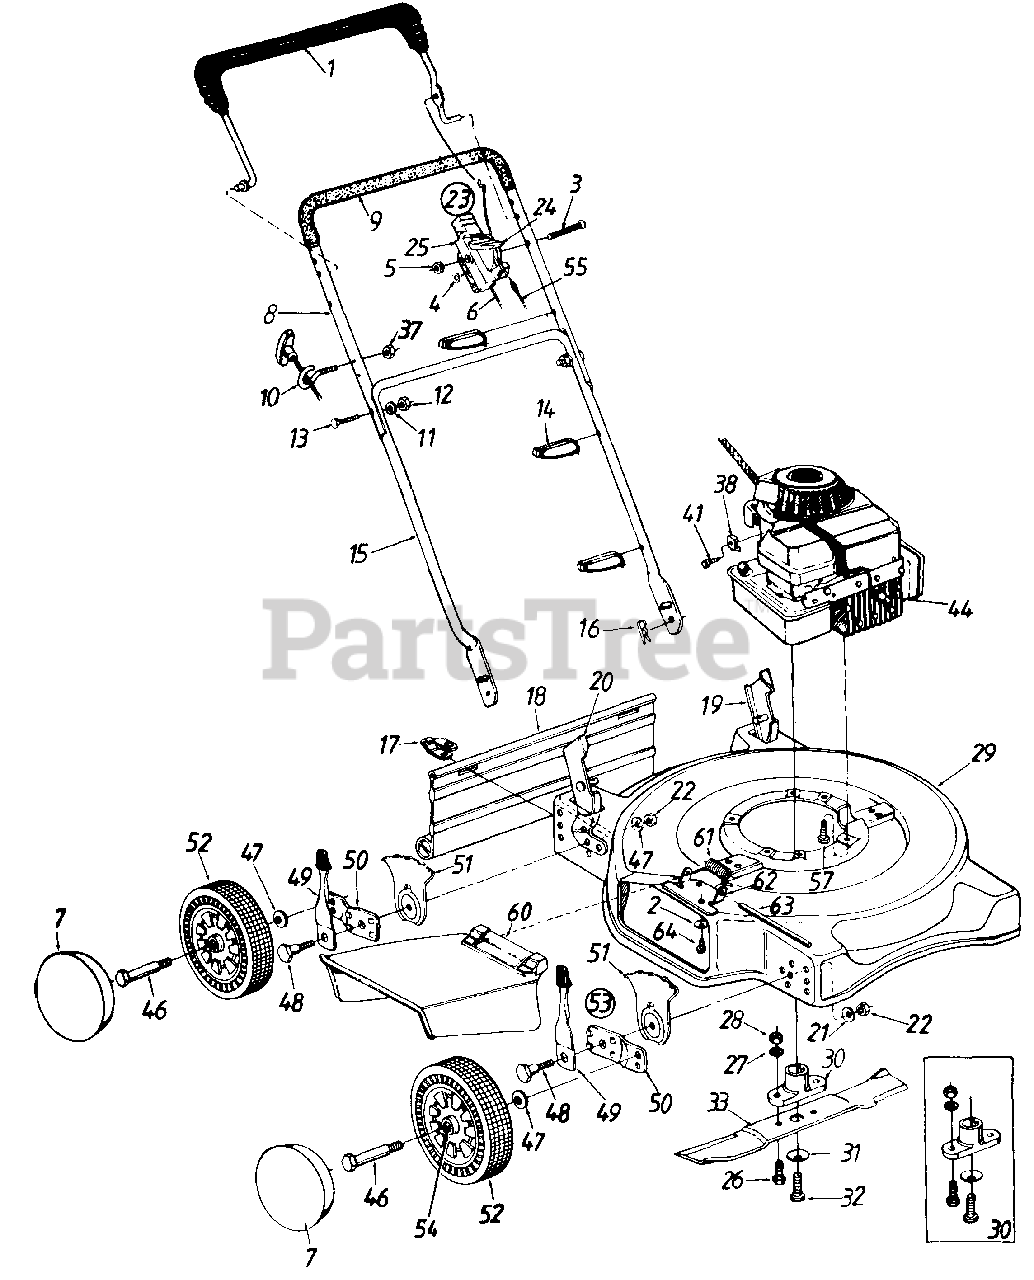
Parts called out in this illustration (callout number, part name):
1	Control Handle Ass'y. w/Plastic
2	Bell-Wash. 1/4" I.D.
3	Oval C-Sunk Mach. Scr.
4	Spr. Wash. .66" I.D.
5	Hex L-Nut 1/4-20 Thd.
6	Throttle Cable - 51"
7	Hub Cap
11	L-Wash. 5/16" I.D.
12	Hex Nut 5/16-18 Thr.
13	Curved Carriage Bolt 5/16-18 x 1.38" Lg.
14	Cable Tie
15	Lower Handle
16	Hairpin Cotter
17	Hinge Clip
18	Rear Flap
19	Handle Bracket Ass'y. - L.H.
20	Handle Bracket Ass'y. - R.H.
21	Bell-Wash. .39" I.D. x 1.38"
22	Hex Nut 3/8-16 Thd.
23	Throttle Box Complete
24	Throttle Lever
25	Throttle Body
26	Hex Bolt 3/8-24 x 1" Lg.
27	L-Wash. 3/8" I.D.
28	Hex Nut 3/8-24 Thd.
31	Bell-Wash. .39" I.D.
32	Hex Bolt 3/8-24 x 1.5" Lg.
33	20" Blade
37	Wing Nut 1/4-20 Thd.
38	Cable Clamp
41	Hex Wash. Hd. Tap Scr. #10-32 x .62" Lg.
44	Spark Plug Boot
47	Bell-Wash. .400" I.D. x .88"
48	Shld. Bolt .50" Dia. x .357"
49	Spring Lever Ass'y. w/Knob
51	Height Adj. Plate
52	Wheel Ass'y. Comp.
53	Height Adj. Ass'y. Comp. - R.F. & L.R.
54	Wheel Bearing
55	Control Cable - 39"
57	Hex L-Wash. Hd. Scr. 3/8-16 x 1.0" Lg.
60	Chute Deflector Ass'y.
61	Torsion Spring
62	Adapter Plate
63	Hinge Pin
64	Hex Self-Tap Scr. 1/4-20 x .5"
